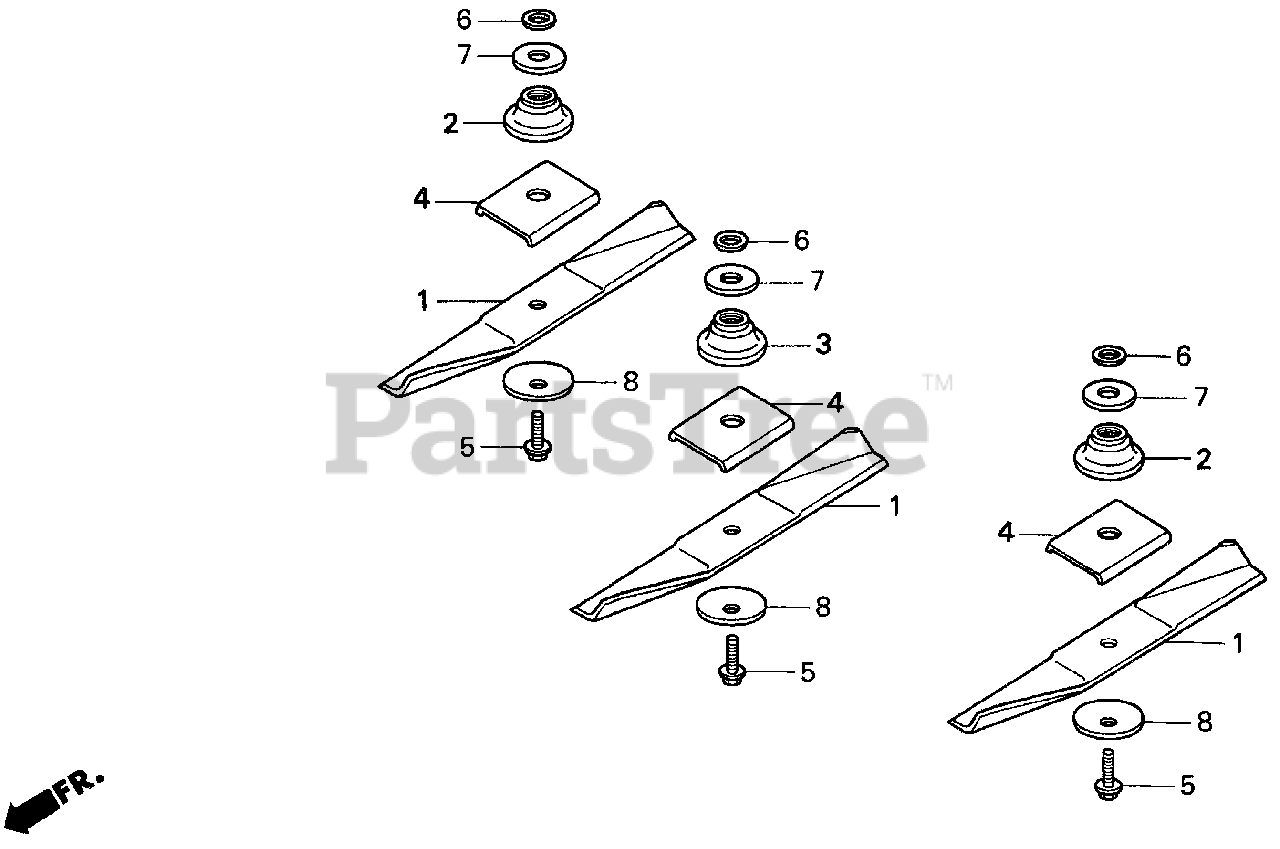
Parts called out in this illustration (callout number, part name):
1	BLADE, ROTARY
2	HOLDER, BLADE
3	HOLDER, BLADE
4	HOLDER, BLADE (B)
5	BOLT, BLADE HOLDER (10X28)
6	WASHER, THRUST (20MM)
7	WASHER, BLADE HOLDER
8	WASHER, BLADE
